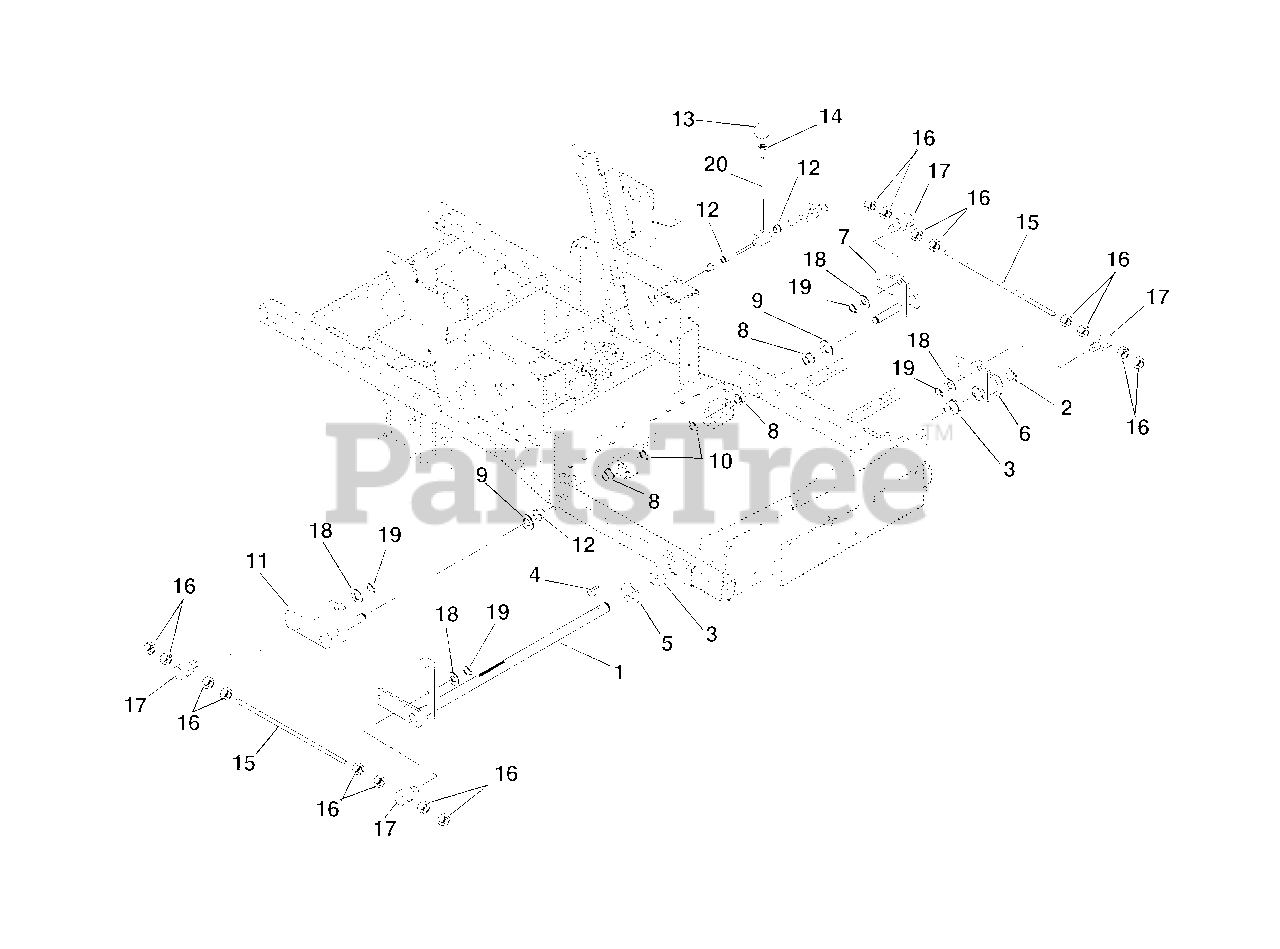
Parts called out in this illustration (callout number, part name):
1	Lift-Mower
2	Ring-Retaining-External 1.00 x .078
3	Bushing-Flange-Nylon 1.020 x 1.385 x .75 x 1.75
4	Key-Woodruff .25 x 1.00
5	Washer-Flat-Steel 1.063 x 2.00 x .134
6	Weldment, Lift Arm-Front
7	Weldment, Lift Arm-Shaft-Left Hand
8	Bushing-Flange-Nylon .762 x 1.0 x .580 x 1.48
9	Washer-Hardened-Steel .758 x 1.23 x .031
10	Ring-Retaining-External .689 x .077
11	Weldment, Lift Arm Shaft-Right Hand
12	Bushing-Flange .63 x 1.00 x .625
13	Knob-Steering Lock
14	Nut-Hex-Jam .375 -16
15	Rod-Lift Assist
16	Nut-Jam .50-13
17	Pivot-Mower Lift
18	Washer-Flat-Steel .630 x 1.005 x .062
19	Ring-Retaining-External .625 x 050
20	Lever-Deck Lift
